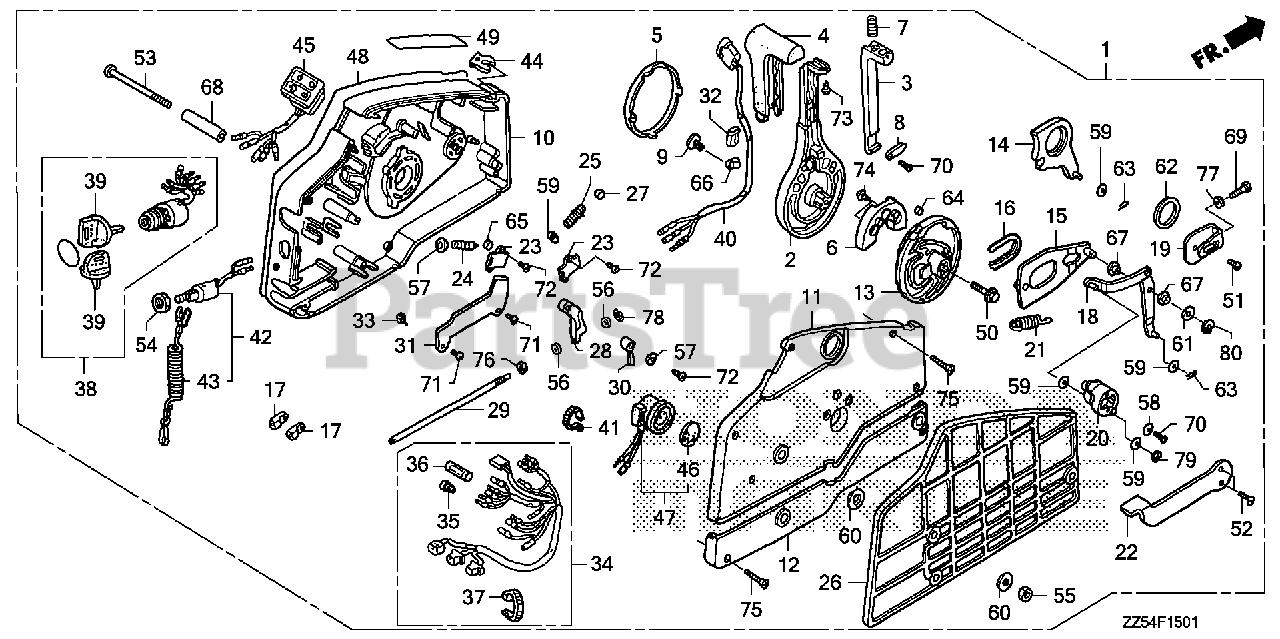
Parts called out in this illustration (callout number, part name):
1	BOX ASSY., REMOTE CONTROL (NHK MEC)
1	BOX ASSY., REMOTE CONTROL (TROLLING CONTROL)(NHK MEC)
1	BOX ASSY., REMOTE CONTROL
2	HANDLE, REMOTE CONTROL
3	LEVER, HANDLE LOCK
4	GRIP, REMOTE CONTROL HANDLE
5	CAP, HANDLE
6	BLOCK, NEUTRAL LOCK
7	SPRING, REMOTE CONTROL HANDLE
8	PLATE, LEVER SETTING
9	CLAMP, HARNESS
10	HOUSING, REMOTE CONTROL BOX (A)
11	HOUSING, REMOTE CONTROL BOX (B)
12	HOUSING, REMOTE CONTROL BOX (C)
13	WHEEL, CONTROL
14	ARM, SHIFT LINK
15	PLATE, SLIDING
16	COLLAR, SLIDING PLATE
17	PIVOT, SHIFT
18	ARM, LINK JOINT
19	BRACKET, LINK JOINT
20	WHEEL, ACCELERATOR
21	SPRING, ACCELERATOR WHEEL
22	LEVER, IDLE
23	PLATE, SPRING SETTING
24	SPRING, SHIFT CLICK
25	SPRING, CHOKE RETURN
26	SPACER, REMOTE CONTROL BOX
27	SPACER, CLICK SPRING
28	BLOCK, THROTTLE FRICTION
29	BOLT, FRICTION
30	SPACER, NEUTRAL SWITCH
31	CLAMP, POWER TILT CORD
32	PIPE, HARNESS GUIDE
33	SPACER, CABLE CLAMP
34	CABLE ASSY., REMOTE CONTROL (B)
35	PLUG, CONNECTOR (INNER)
36	PLUG, CONNECTOR (OUTER)
37	TIE, CABLE (2.4X92) (NATURAL)
38	SWITCH ASSY., COMBINATION
39	KEY ASSY., COMBINATION SWITCH (35100-ZV5-003 ONLY)
40	SWITCH ASSY., POWER TRIM-TILT
41	BAND (BLACK 3.5X140)
42	SWITCH ASSY., EMERGENCY STOP
43	WIRE, EMERGENCY
44	CLIP, EMERGENCY LOCK
45	LAMP ASSY., INDICATION
46	PLATE, TURN SIGNAL BUZZER
47	BUZZER, WARNING
48	PLATE, REMOTE CONTROL (CAUTION PICT=SILVER)
48	PLATE, REMOTE CONTROL (COUTION COLOR=RED & YELLOW)
49	MARK, FAST IDLE
50	BOLT, FLANGE (8X35)
51	SCREW, PAN (6X10)
52	SCREW, FLAT (5X12)
53	SCREW (6X95)
54	NUT, HEX. (16MM)
55	NUT, HEX. (6MM)
56	WASHER, PLAIN (4MM)
57	WASHER, PLAIN (5MM)
58	WASHER, PLAIN (5MM)
59	WASHER, PLAIN (6MM)
60	WASHER (6MM)
61	WASHER, PLAIN (8MM)
62	WASHER (28MM)
63	PIN, LOCK (6MM)
64	PIN (6X6)
65	ROLLER, CLICK
66	CLIP, WIRE HARNESS (6.3MM)
67	COLLAR, LINK JOINT
68	COLLAR, DISTANCE (6X10X43.5)
69	BOLT, HEX. (5X16)
70	SCREW, PAN (5X10)
71	SCREW, TAPPING (5X8)
72	SCREW, TAPPING (5X10)
73	SCREW, TAPPING (5X12)
74	SCREW, TAPPING (6X16)
75	SCREW, TAPPING (5X25)
76	NUT, HEX. (6MM)
77	NUT, HEX. (5MM)
78	E-RING (3MM)
79	E-RING (4MM)
80	E-RING (7MM)
